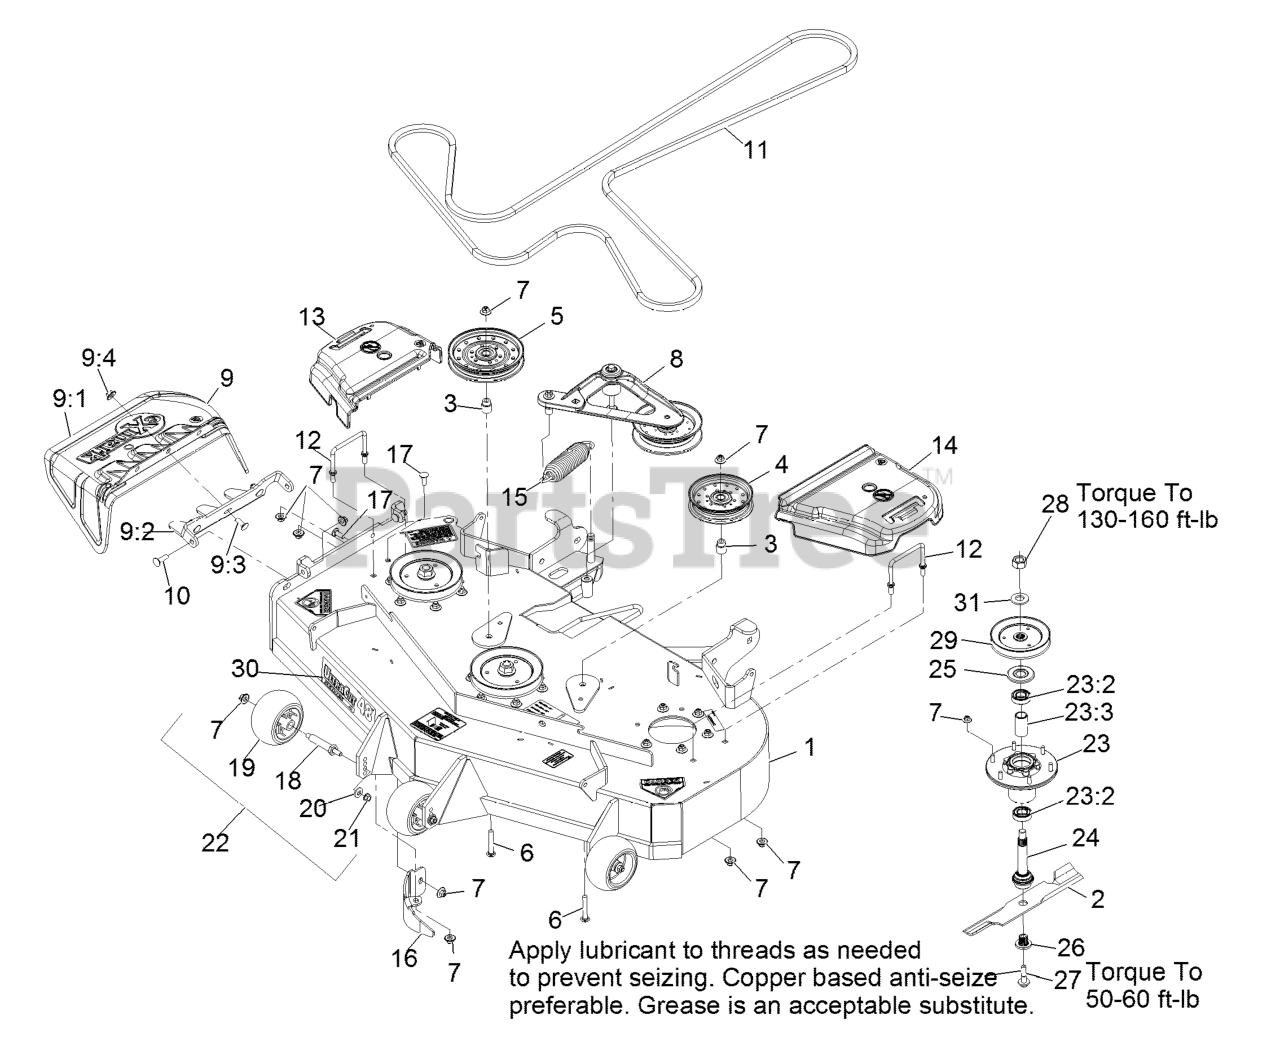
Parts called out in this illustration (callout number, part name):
1	ASM,DECK W/DECALS 48
3	BUSHING-IDLER
6	SCREW-CARR
7	Nut-Nyloc 3/8-16 Flg
8	DECK IDLER ASM
9	ASM,DISCHARGE CHUTE
9:1	CHUTE,DISCHARGE
9:2	BRACKET,DISCHARGE CHUTE
9:3	SCREW-CARR
9:4	Nut-Nyloc 3/8-16 Flg
10	Bolt-Carriage 3/8-16 X 1 1/4
11	BELT
12	WIREFORM-COVER
13	COVER-BELT, RH
14	COVER-BELT, LH
15	SPRING-EXTENSION
16	BAFFLE-DOGLEG,LZS LZX VT4
17	SCREW-CARR
19	ROLLER-SCALP, ANTI
20	WASHER-BELLEVILLE
21	NUT-HHF, WHIZ
23	ASM-CUTTER HSG WITH BEARINGS
23:2	BEARING-BALL
23:3	SPACER-BEARING
24	ASM-SPINDLE AND SEAL
25	GUARD,BEARING TOP .989
26	BUSHING,SPLINED
27	SCREW,SEMS 1/2-20 X 2.19
28	NUT-HEX
29	SHEAVE,BLADE DRIVE 5.90
30	DECAL,ULTRACUT 48 SERIES
